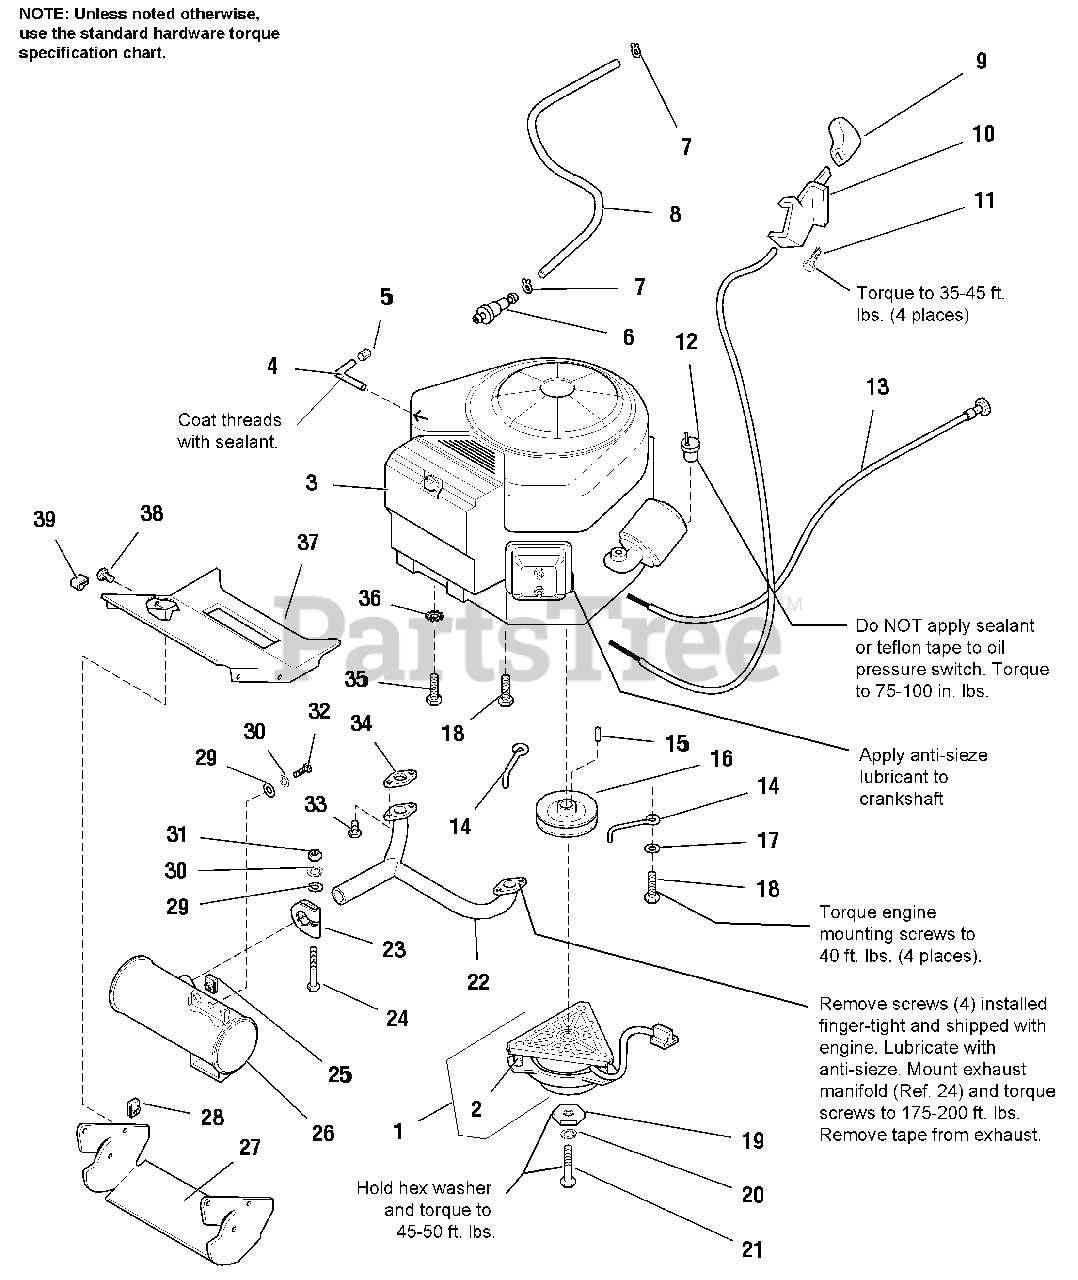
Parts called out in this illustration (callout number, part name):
1	ELECTRIC CLUTCH
2	SPRING & NUT KIT
3	ENGINE, 14HP or 16HP Briggs & Stratton V-Twin Vanguard
4	DRAIN PIPE, Oil
6	FUEL FILTER
7	CLAMP, Hose
8	HOSE, Fuel, 45-1/2" Long
9	KNOB, Throttle
10	THROTTLE CONTROL ASSY.
11	CAPSCREW, Hex Washer Hd, Plastite, 1/4-20 x 1/2
12	SWITCH, Oil Pressure
13	CABLE, Choke Control
15	KEY, Hi-Pro
16	PULLEY ASSY.
17	WASHER, Plain, 13/32
18	CAPSCREW, Taptite, 3/8-16 x 1-1/2
19	WASHER, Hex
20	LOCKWASHER, 7/16
21	CAPSCREW, 7/16-20 x 2-1/2
22	MANIFOLD, Exhaust
23	CLAMP, Muffler
24	CARRIAGE BOLT, 5/16-18 x 2-3/4
25	PAL NUT, 5/16-18
26	MUFFLER ASSY.
27	DUCT, Lower Muffler
28	PAL NUT, 1/4-20
29	WASHER, 5/16
30	LOCKWASHER, 5/16
31	NUT, Hex, 5/16-18
32	CAPSCREW, Hex Hd, 5/16-18 x 1
33	CAPSCREW, Metric
34	GASKET, Exhaust Manifold
35	CAPSCREW, Taptite, 3/8-16 x 1-1/2
36	LOCKWASHER, External Tooth
37	DUCT, Upper Muffler
38	CAPSCREW, Hex Flange Hd, Whizlock, 1/4-20 x 5/8
39	CLIP
